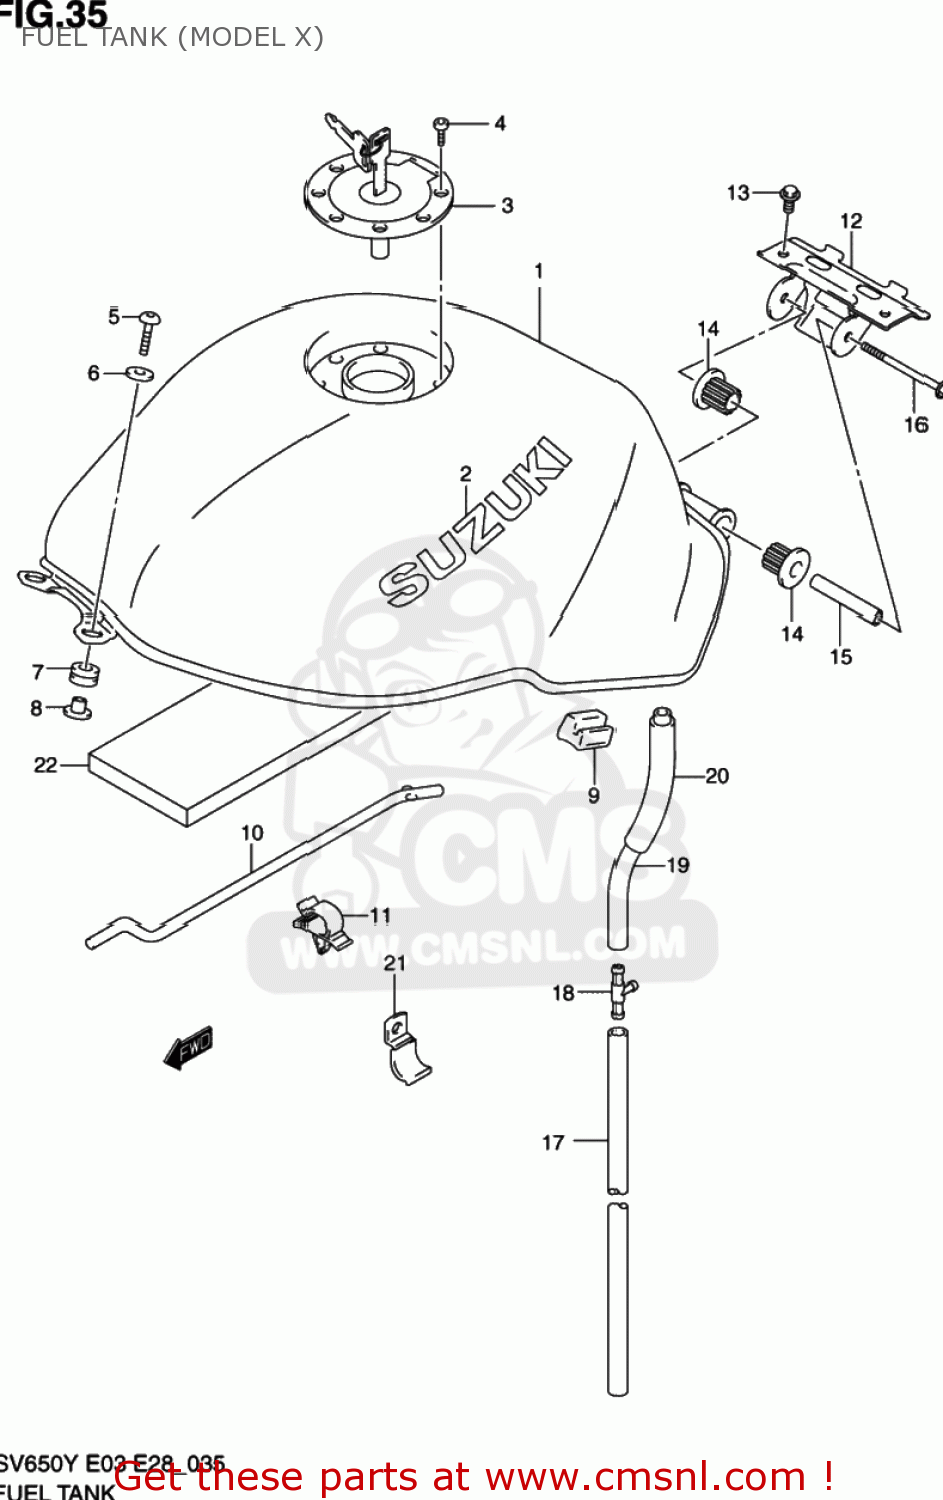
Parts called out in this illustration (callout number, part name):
1	TANK ASSY,FUEL(BLUE)
2	EMBLEM,FUEL TANK
3	CAP SET,FUEL TANK
4	BOLT(5X20)
5	SCREW(6X25)
6	WASHER(6.5X22X1.6)
7	CUSHION,FUEL TANK FR
8	SPACER,FUEL TANK FR
9	CUSHION,FUEL TANK SIDE
10	STAY,FUEL TANK
11	CLAMP
12	BRACKET,FUEL TANK RR
13	BOLT
14	CUSHION,FUEL TANK RR
15	SPACER,FUEL TANK RR
16	BOLT
17	HOSE(7X10.2X600)
18	3-WAY [FILTER TO PUMP)
19	HOSE(7X10.2X600)
20	PROTECTOR(14.5X15.5X600)
21	CLAMP,DRAIN HOSE
22	SHIELD,FUEL TANK FR
